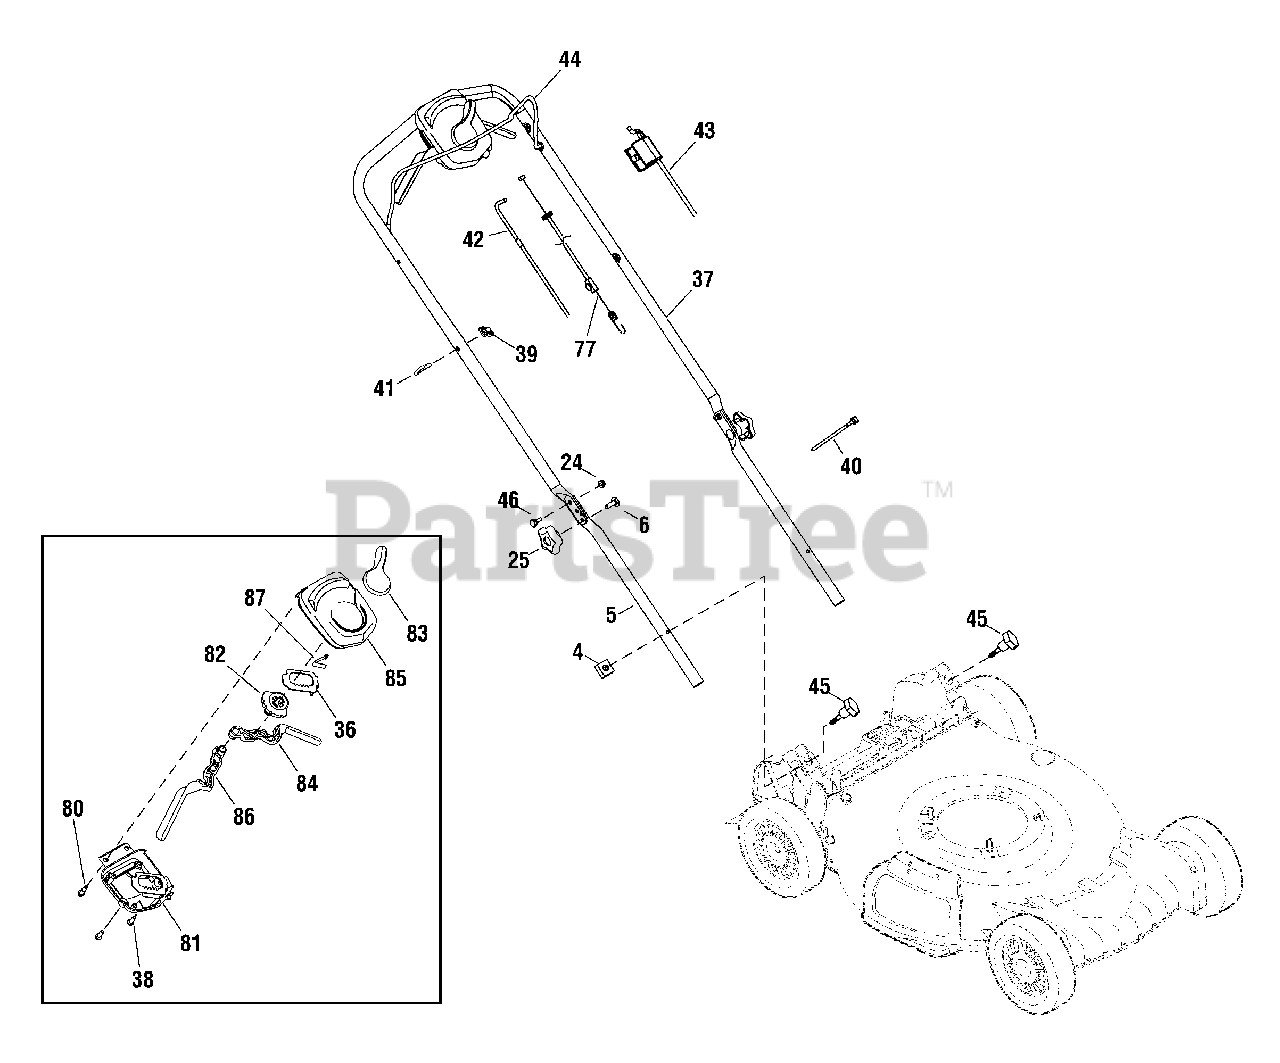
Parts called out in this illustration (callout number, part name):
4	NUT, Square, 1/4-20
5	HANDLE, Lower
6	BOLT, Carriage, 5/16-18 x 1, GR5
24	NUT, Nylock Flanged, 1/4-20
25	KNOB, Wing, 5/16-18
36	PLATE, Cable Adjust
37	HANDLE, Upper
38	SCREW, 1/4-15X3/4, Self-Tapping, BZ
39	KNOB, 1/4-20
40	TIE, Self Lock
41	GUIDE, Rope
42	CABLE, Drive
43	CABLE, OPC Engine Brake
44	BAIL, Blade Control
45	NUT, Wing
46	BOLT, Shoulder, 1/4-20
77	CABLE, Speed Adjustment
80	SCREW, Shoulder, 1/4-15 x 1
81	HOUSING, Lower
82	ACTUATOR, Speed Adjust
83	LEVER, Speed Select
84	LEVER, Control, LH
85	HOUSING, Upper
86	LEVER, Control, RH
